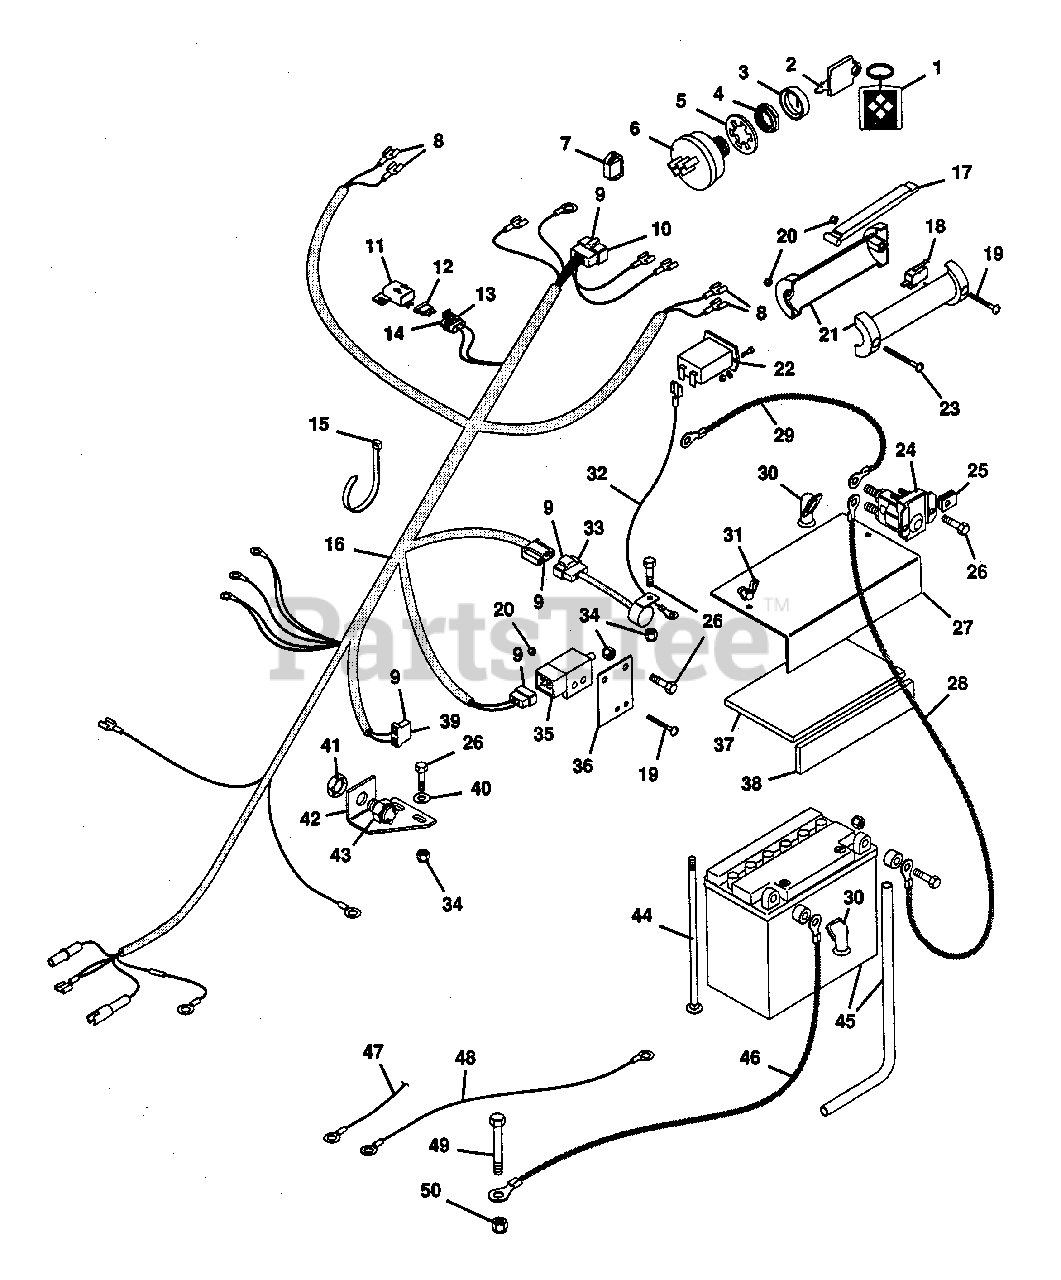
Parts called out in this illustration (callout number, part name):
1	Chain, Key
2	Key, Ignition Switch
3	Boot, for 9/16 Switch
4	Nut, 5/8-32 for Switch
5	Washer, Lock 5/8 Int. Th.
6	Switch, Ignition w/Ground
7	Light, Indicator
8	Terminal, Female
9	Terminal
10	Connector
11	Cover
12	Fuse, 25 Amp
13	Assembly, Connector
14	Terminal, for 10-12 Ga. Wire
15	Tie Wrap, Black
16	Harness, Wiring
17	Lever
18	Switch
19	Screw, Machine 10-24x.625 PHD
20	Nut, Lock 10-24
21	Handle
22	Hourmeter
23	Screw, Mach. 10-24x1.50 PHDCR
24	Switch, Magnetic
25	Nut, Speed 1/4-20
26	Bolt, Hex 1/4-20x.750
27	Cover, Battery
28	Cable, Battery to Solenoid
29	Cable, Solenoid to Starter
30	Boot, Battery Cable
31	Nut, Wing 1/4-20
32	Wire, Instrument Panel
33	Module, Interlock
34	Nut, Lock 1/4-20
35	Switch, Interlock
36	Bracket, Interlock Switch
37	Pad, Battery
38	Pad, Battery
39	Connector, 2-Wire Switch
40	Washer, Flat .281 x.625x.065
41	Nut, Stamped 9/16-18
42	Bracket, Interlock Switch
43	Switch, Interlock
44	Bolt, 1/4-20x7.00 Rd Hd Sq Nk
45	Battery, 12 Volt
46	Cable, Negative Battery
47	Terminal, Ring Tongue
48	Wire, Ground
49	Bolt, Hex 5/16-18x2.00
50	Nut, Lock 5/16-18
